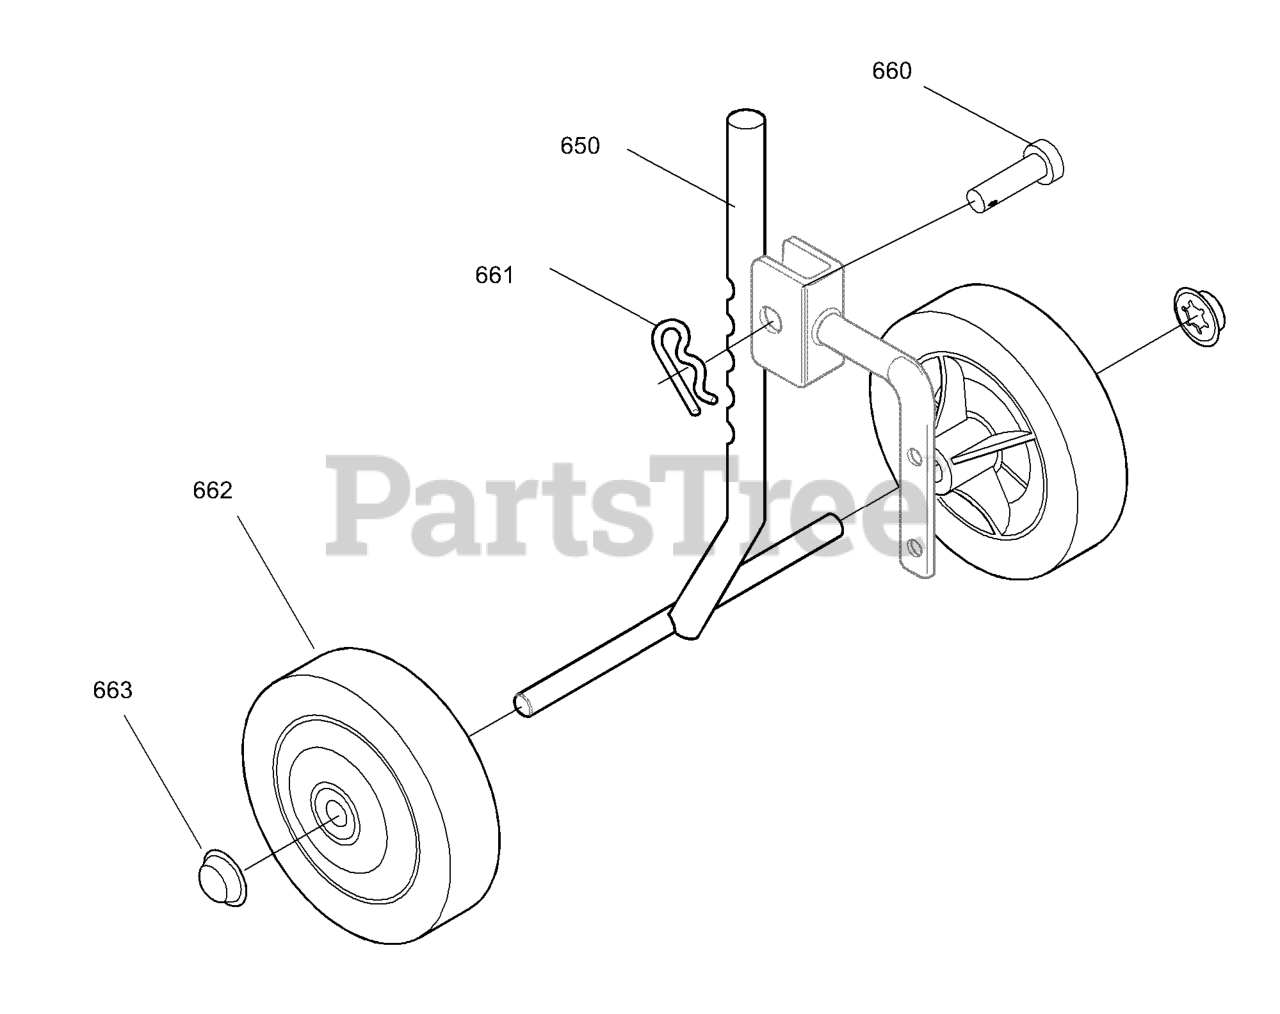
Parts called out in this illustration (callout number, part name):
650	Wheel Support Assy.
660	Clevis Pin
661	Hair Pin
662	Tire & Rim
663	Push On Nut
